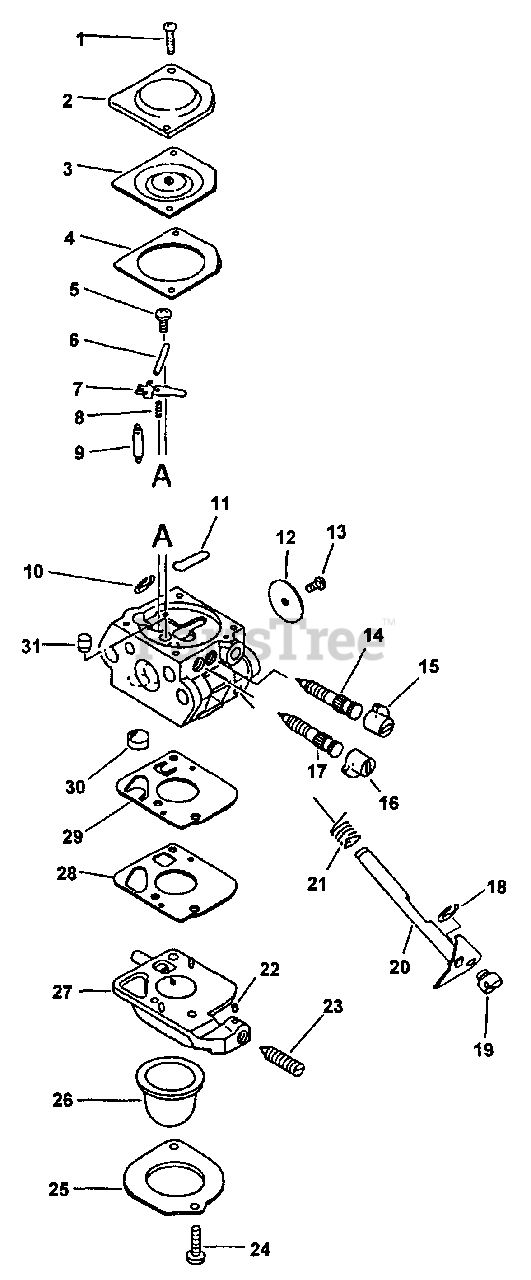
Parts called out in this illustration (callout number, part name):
2	COVER, METERING
3	DIAPHRAGM, METERING
4	GASKET, METERING
5	SCREW, METERING LEVER PIN
6	PIN, METERING LEVER
7	LEVER, METERING
8	SPRING, METERING LEVER
9	VALVE, NEEDLE
10	RING, RETAINING
11	PLUG, WELCH
12	VALVE, THROTTLE
14	NEEDLE - LOW SPEED
15	CAP, LIMITER
16	CAP, LIMITER
17	NEEDLE - HIGH SPEED
18	RING, RETAINING
20	SHAFT, THROTTLE
21	SPRING, RETURN
22	PIECE, FRICTION
23	SCREW, IDLE ADJUST
24	SCREW, RETAINER
25	RETAINER, PURGE BULB
26	BULB, PURGE
27	BASE, PURGE
28	GASKET, PURGE
29	DIAPHRAGM, PURGE
30	STRAINER
31	NOZZLE, CHECK VALVE
